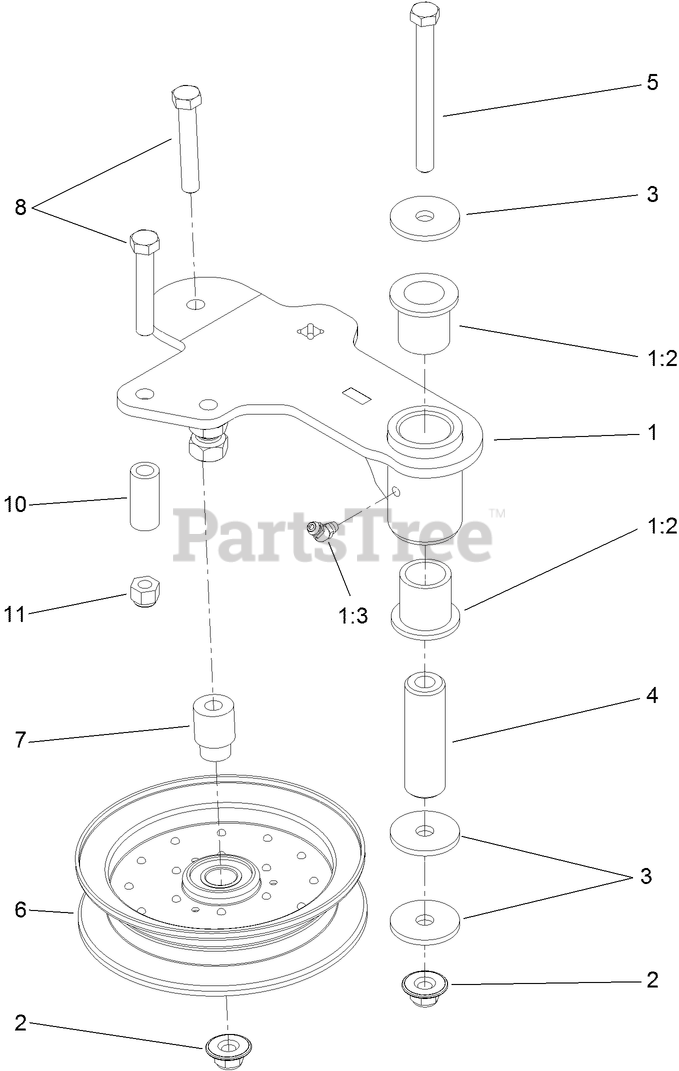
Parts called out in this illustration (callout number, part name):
1	IDLER ARM ASM
1:2	BEARING-FLANGED
1:3	FITTING-GREASE
2	NUT-FLANGE, NI
3	WASHER
4	SPACER-PLAIN
5	SCREW-HH
6	IDLER-PULLEY, FLANGED
7	MOUNT-PULLEY
8	SCREW-HH
10	SPACER
11	NUT-LOCK, NI
